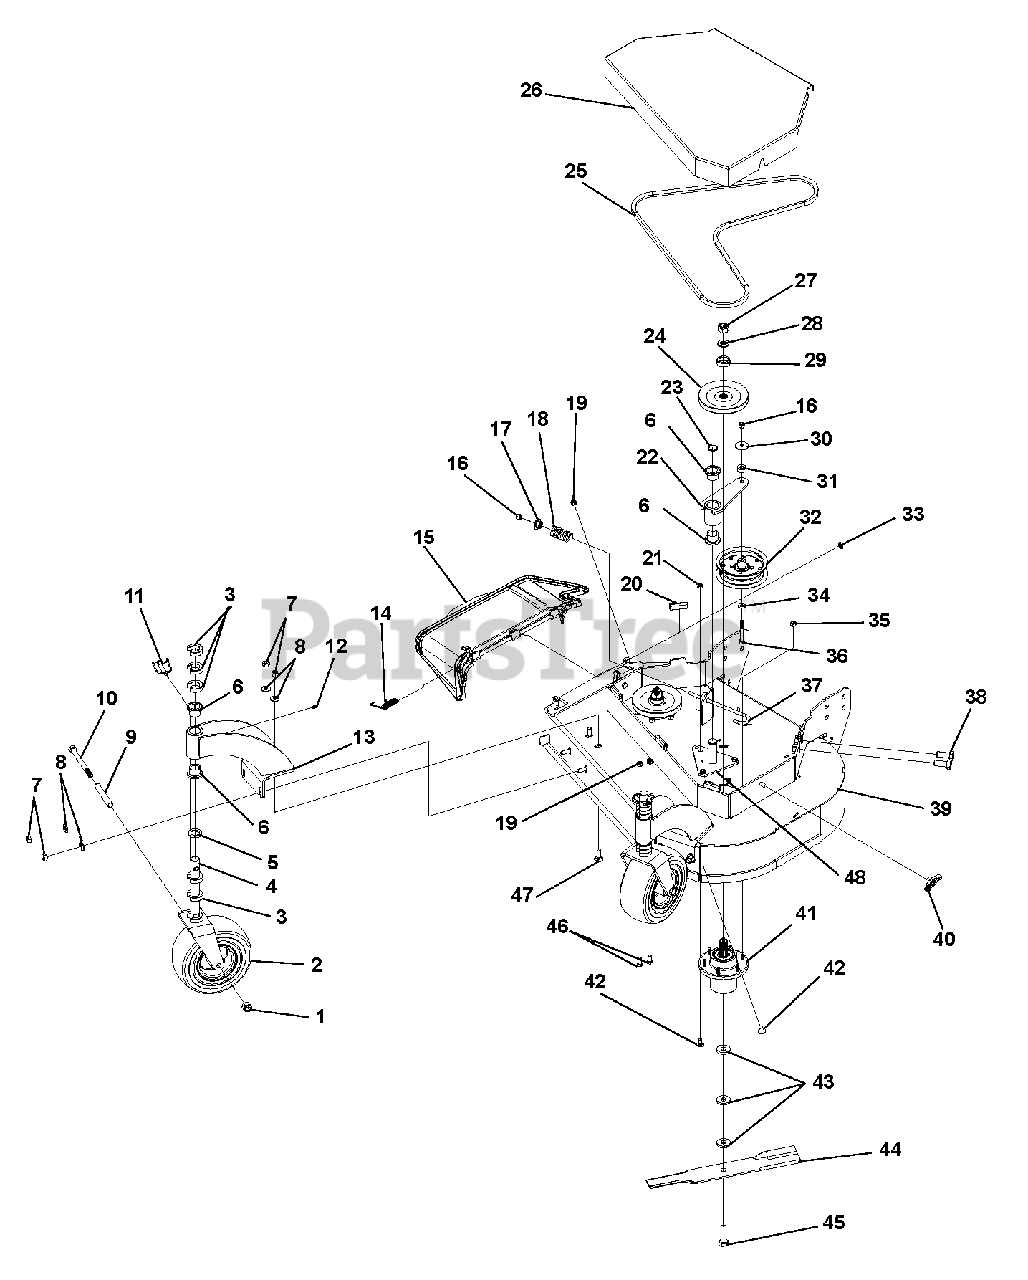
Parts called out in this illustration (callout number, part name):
1	Locknut, .50-13 Nyloc
2	Assembly, Wheel and Tire 9 x 3.5
3	C-Spacer, 1.00 x 1.77 x .500
4	Weldment, Caster Yoke w/Gravely Paint
5	Bushing, 1.03 x 1.50 x .179
6	Bearing, Flange 1.00 x 1.25 x 1.00
7	Locknut, .4375-14 Crown
8	Washer, .375 Regular Flat
9	Tube, Caster Axle
10	Bolt, .50-13 x 5.50 Hex 5
11	Pin, LNC .438 x 2.00
12	Fitting, .25-28 STRGT Grease Zerk
13	Weldment, Caster SUPP w/Gravely Paint
14	Spring, Torsion .460 x .138
15	Chute Discharge Assembly
16	Locknut, .38-16 Nyloc
17	Keeper, Spring
18	Spring, COM 1.22 x .162 x 2.50
19	Locknut, .38-16 Crown
20	Trim, 1/4" Trim-LOK
21	Nut, Locking-Jam-Center .375-16
22	Weldment, Idler Arm
23	Snap Ring, 1.00 x .042 External
24	Pulley, Narrow Spline
25	Belt, HB 80.3 Elbow AMD OHR
26	Shield, Belt 32/36 Gear Gravely
27	Locknut, .75-16 Crown
28	Washer, .75 x 1.3125 x .120
29	Spacer, Spindle Top-Pulley
30	Washer, Flat .375 x 1.50 x .063
31	Bushing, .380 x 1.00 x .410
32	Pulley, Flat 5.00 x .375 W/BRG
33	Retainer
34	Washer, .406 x .813 x .065 Flat
35	Nut, .38-16 Standard Hex Grade 5
36	Bolt, .38-16 x 2.75 Hex 5
37	J-Bolt, .38-16 x 7.88
38	Bolt, Hex .625-11 1.5 Grade 8
39	36" Gravely Gear Deck with Decals
40	Knob, .38-16 Insert
41	Assembly, Spindle Housing
42	Bolt, .38-16 x .750 CRG 5 LN
43	Washer, .630 x 1.50 x .250 Flat
44	Blade, 18.000 x .80 Lift
45	Bolt, .625-11 x 2.00 Hex 8
46	Bolt, .38-16 x .750 Hex 5
47	Bolt, .4375-14 x 1.25 CRG 5
48	Weldment, Idler Pivot Mount
